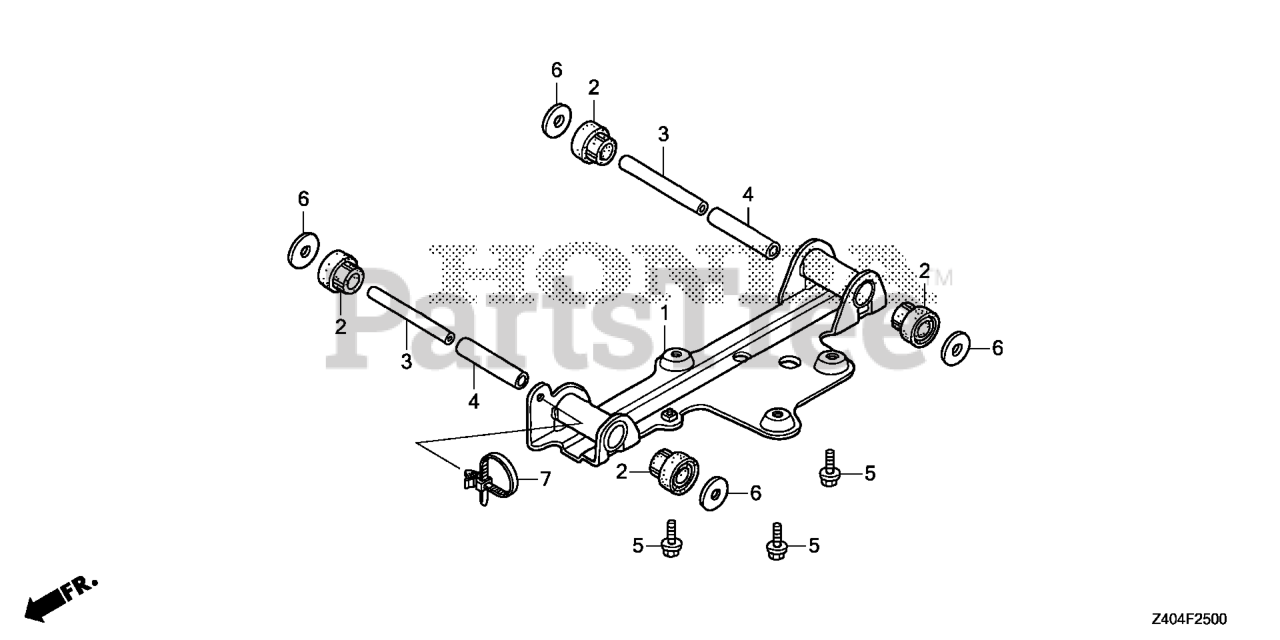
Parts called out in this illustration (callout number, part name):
1	BED, ENGINE
2	INSULATOR, ENGINE BED
3	COLLAR A, INSULATOR
4	COLLAR C, INSULATOR
5	BOLT, FLANGE (6X16)
6	WASHER, SPROCKET SETTING
7	STRAP, CABLE (118MM) *NH1L* (Honda Code 1170653). (BLACK)
